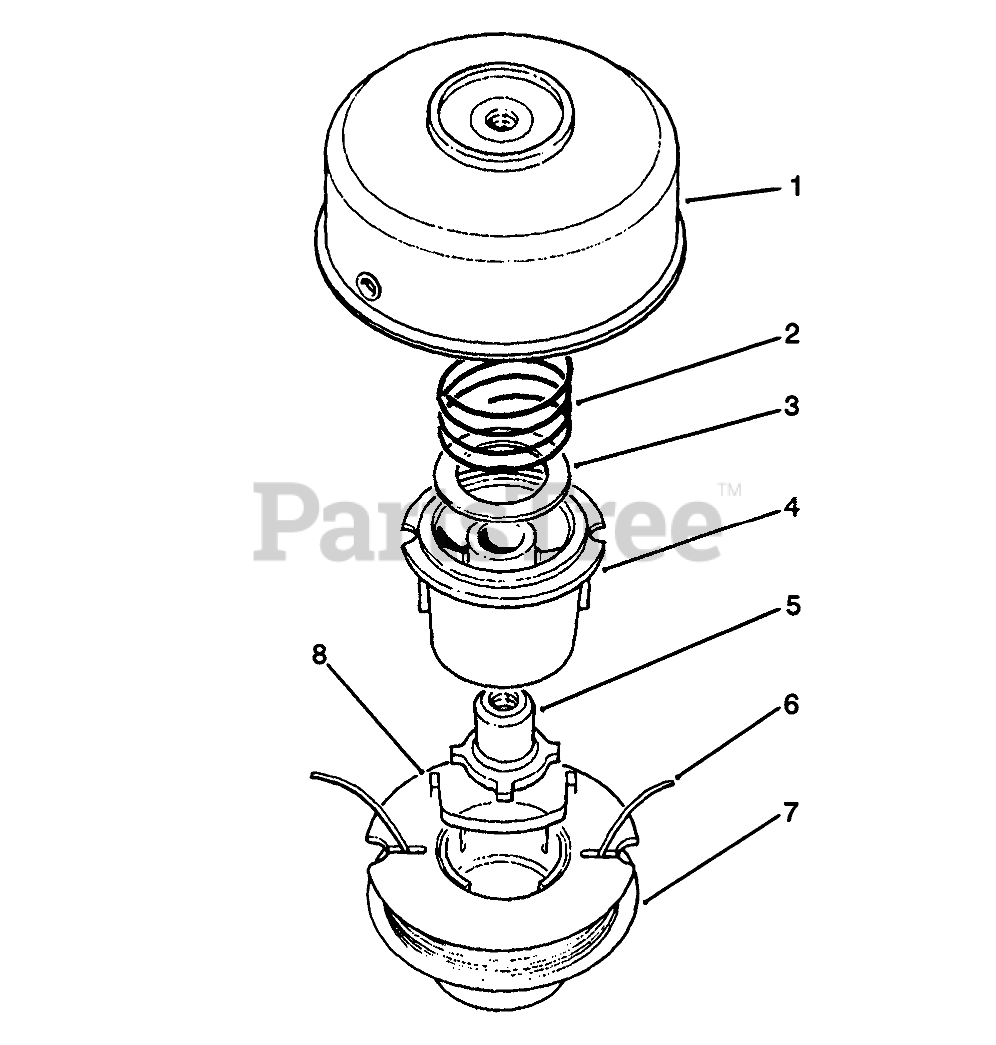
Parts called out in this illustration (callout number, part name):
1	ASM - TRIMMER DRUM & EYELET
2	SPRING
3	WASHER-FLAT
4	SPOOL CORE
5	LH DRIVER
6	REPL LINE PKG
7	Spool Prewound .08 Dia. 38- (Incl. Ref. #6 & 8)
8	SADDLE-SPOOL CAP
